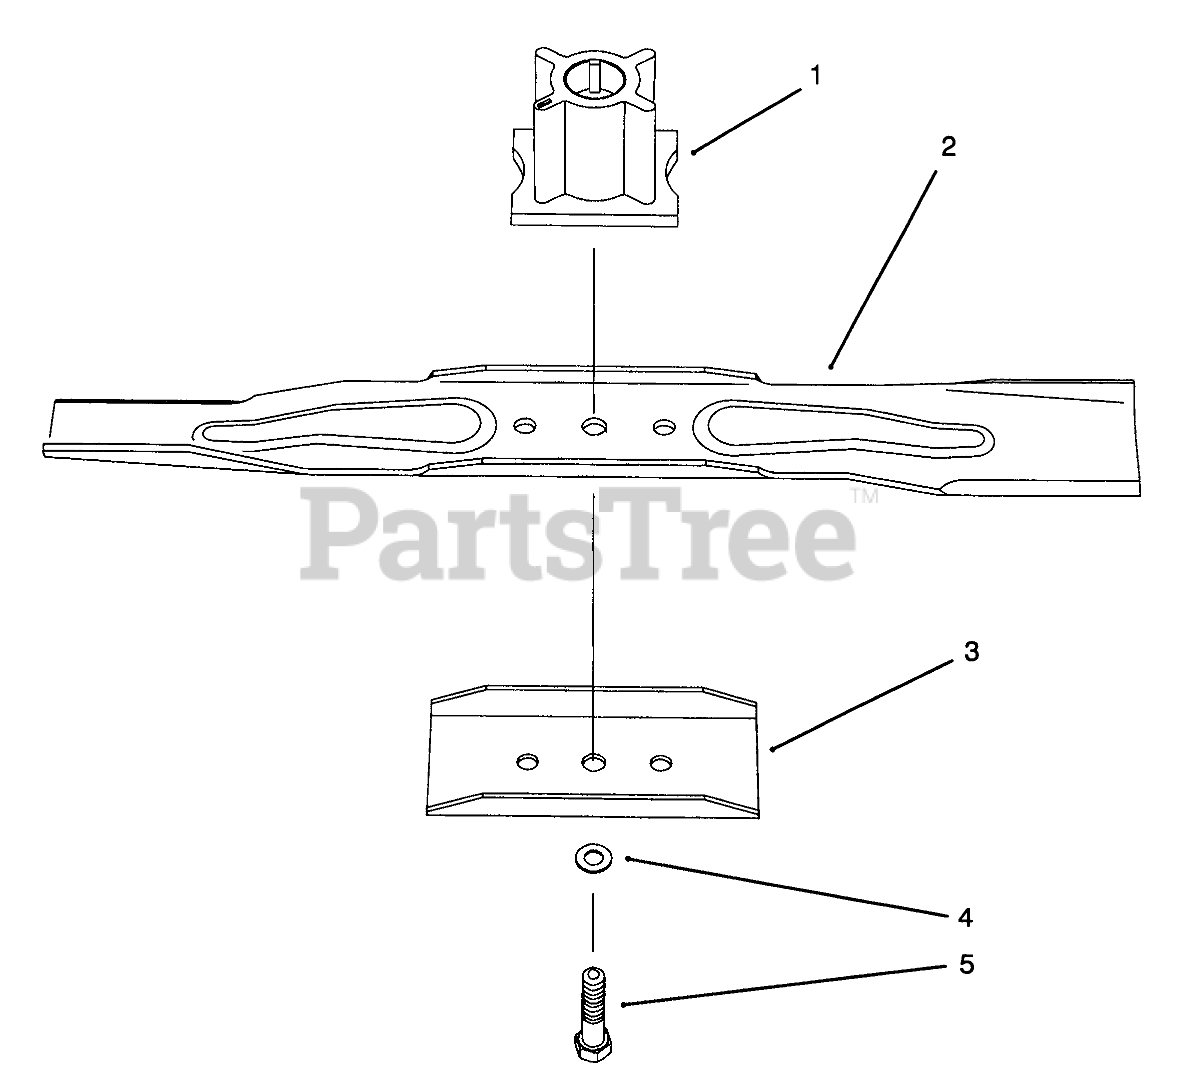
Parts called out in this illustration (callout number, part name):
1	BLADE RETAINER - 25 MM
2	Blade
3	Stiffener
4	WASHER-LOCK
5	BOLT-BLADE
